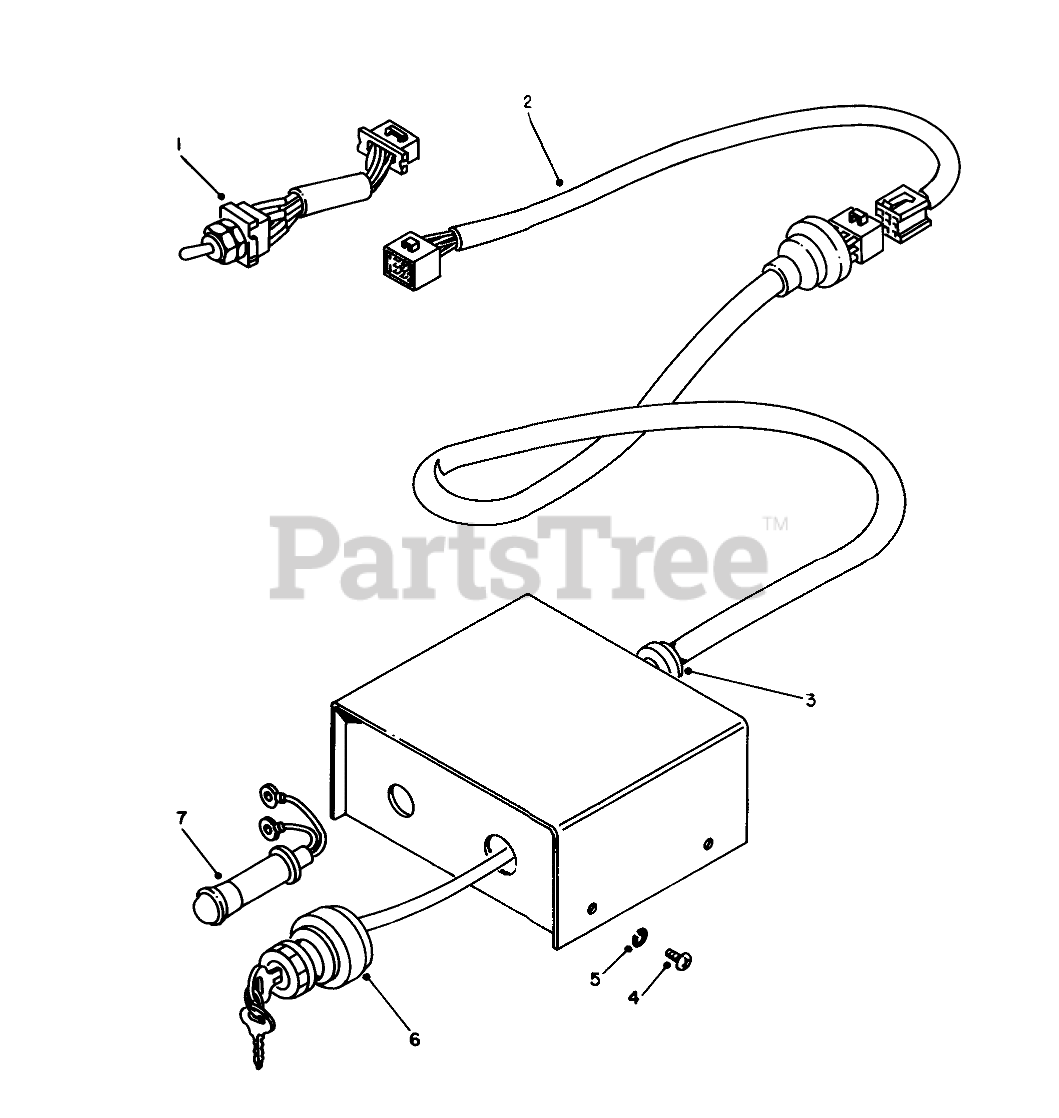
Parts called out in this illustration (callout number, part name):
1	Switch-Remote Select
2	Cable-Extension
3	Grommet
4	Screw
5	WASHER-LOCK
6	Switch-Engine
7	Holder
